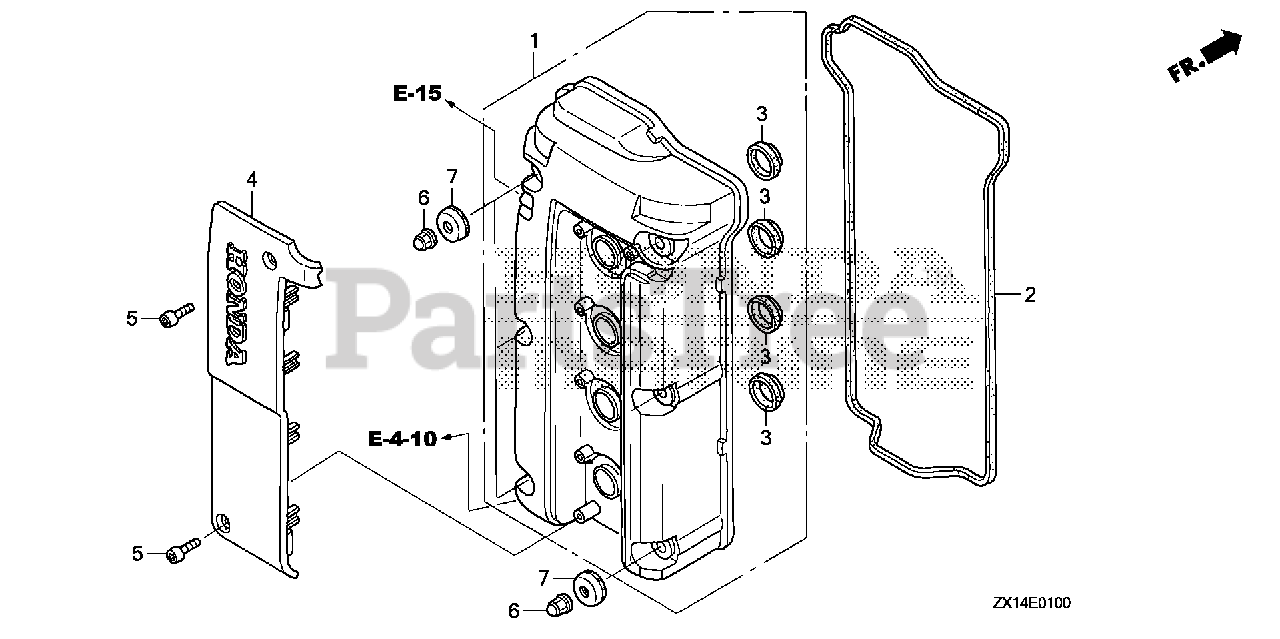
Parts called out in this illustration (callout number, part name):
1	COVER, CYLINDER HEAD *NH8* (DARK GRAY) (FOR 14540-RWC-A02)
2	GASKET, CYLINDER HEAD COVER
3	SEAL, SPARK PLUG TUBE (NOK)
4	COVER, PLUG HOLE COIL
5	BOLT, SOCKET (6X25)
6	NUT, FLANGE CAP (6MM)
7	WASHER, HEAD COVER
